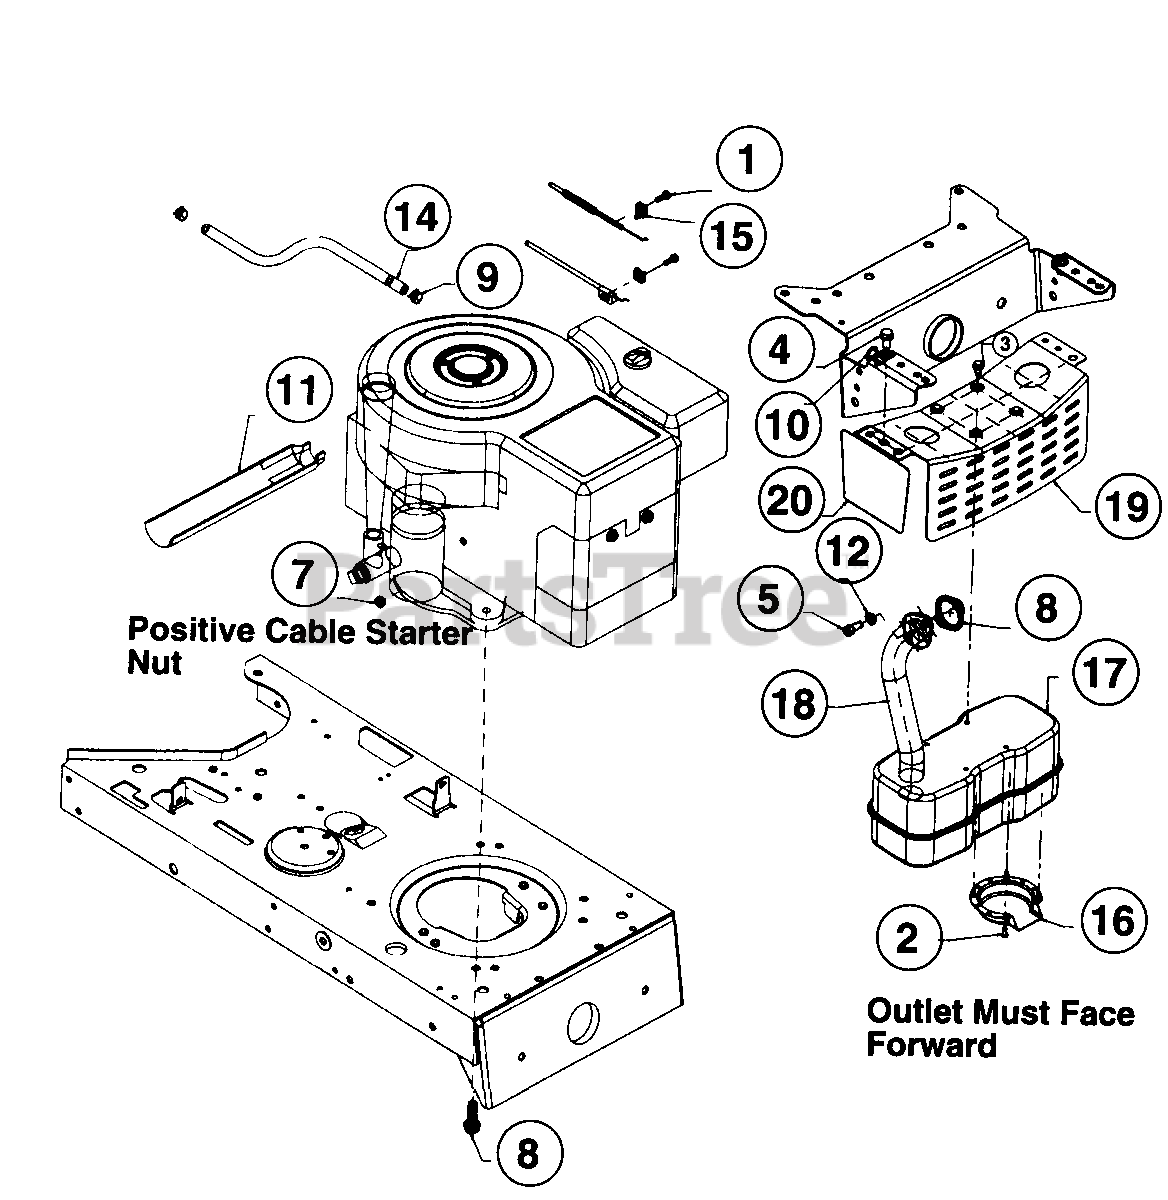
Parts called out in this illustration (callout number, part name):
1	Hex Wash. Scr. #10-32 x .62"
2	Hex Tap Scr. #8-32 x .38" Lg.
4	Hex TT-Tap Scr. 5/16-18 x .62"
5	Socket Head Scr. 5/16-18 x .62"
7	Hex Sems Scr. 1/4-20 Thd.
8	Gasket
9	Hose Clamp
10	Clamp
11	Oil Drain Sleeve
12	Lock Washer 5/16" I.D.
14	Fuel Line 12" Lg.
15	Casing Clamp
16	Muffler Deflector
17	Muffler
18	Exhaust Pipe
19	Muffler Brkt.
20	Shield Brkt.
